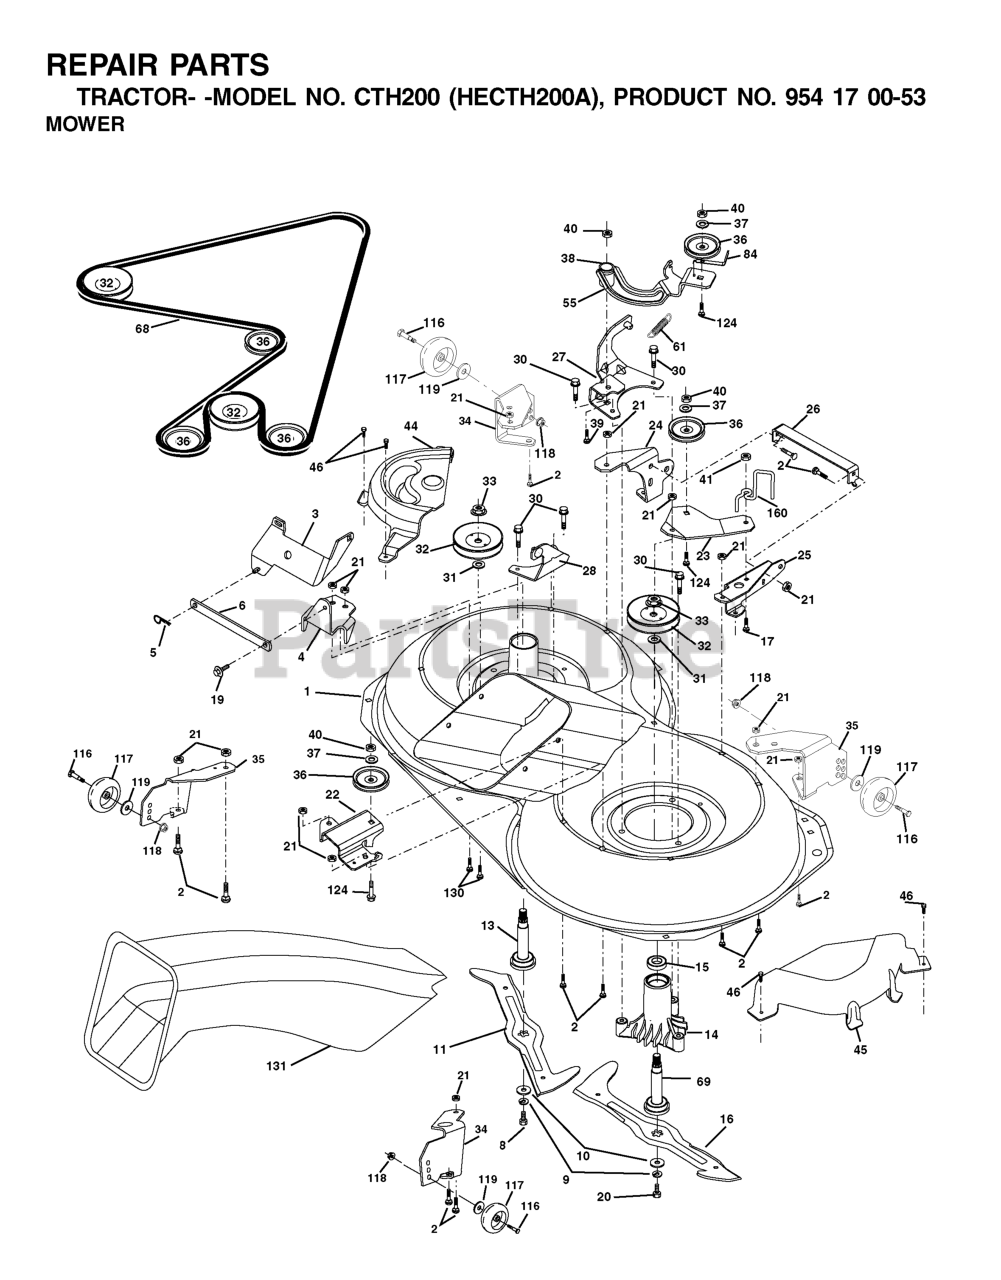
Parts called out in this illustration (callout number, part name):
2	RP BOLT 5/16-18 X3/4 ZN/YEL GR
5	RETAINER SPRING
6	BAR.SWAY.92.CRD
8	BLADE BOLT
9	LOCKWASHER
10	WASHER.BLADE
11	BLADE, LH (CTH150)
13	SHAFT ASM VENT
14	HOUSING.MANDREL.VENTED (MACHD)
16	RP BLADE RH (CTH150)
17	BOLT.3/8-14X1.25
19	BOLT SHD 5/16-18
21	LOCKNUT
22	BRACKET.IDLER.RR.107.CRD
25	BRACKET.SUSPENSION.RF.107.CRD
26	BRACE.SUPT.SUSP.FRT.CRD
28	BRACKET
30	SCREW, WASHER HEAD
31	WASHER
33	NUT, FLG TOPLOCK 9/16"
36	PULLEY.IDLER.4.25
37	WASHER
41	NUT LOCK FLG 3/8-16 UNC
45	COVER.MANDREL.RH.CRD
46	SCREW.1/4-20X5/8
55	ARM.IDLER.107.CRD
68	HEX-BELT 107 MOWER
69	SHAFT.ASM.W/LWR.BRG.RH.THREAD
84	KEEPER, BELT IDLER
116	BOLT, SHOULDER
117	WHEEL GAGE DONUT
118	LOCKNUT
119	WASHER.5/16.FLAT.STE.STD.
124	BOLT.3/8-16X1.50
130	BOLT.CARR.SQNK.5/16-18UNC.X3/4
131	CHUTE BAGGER
